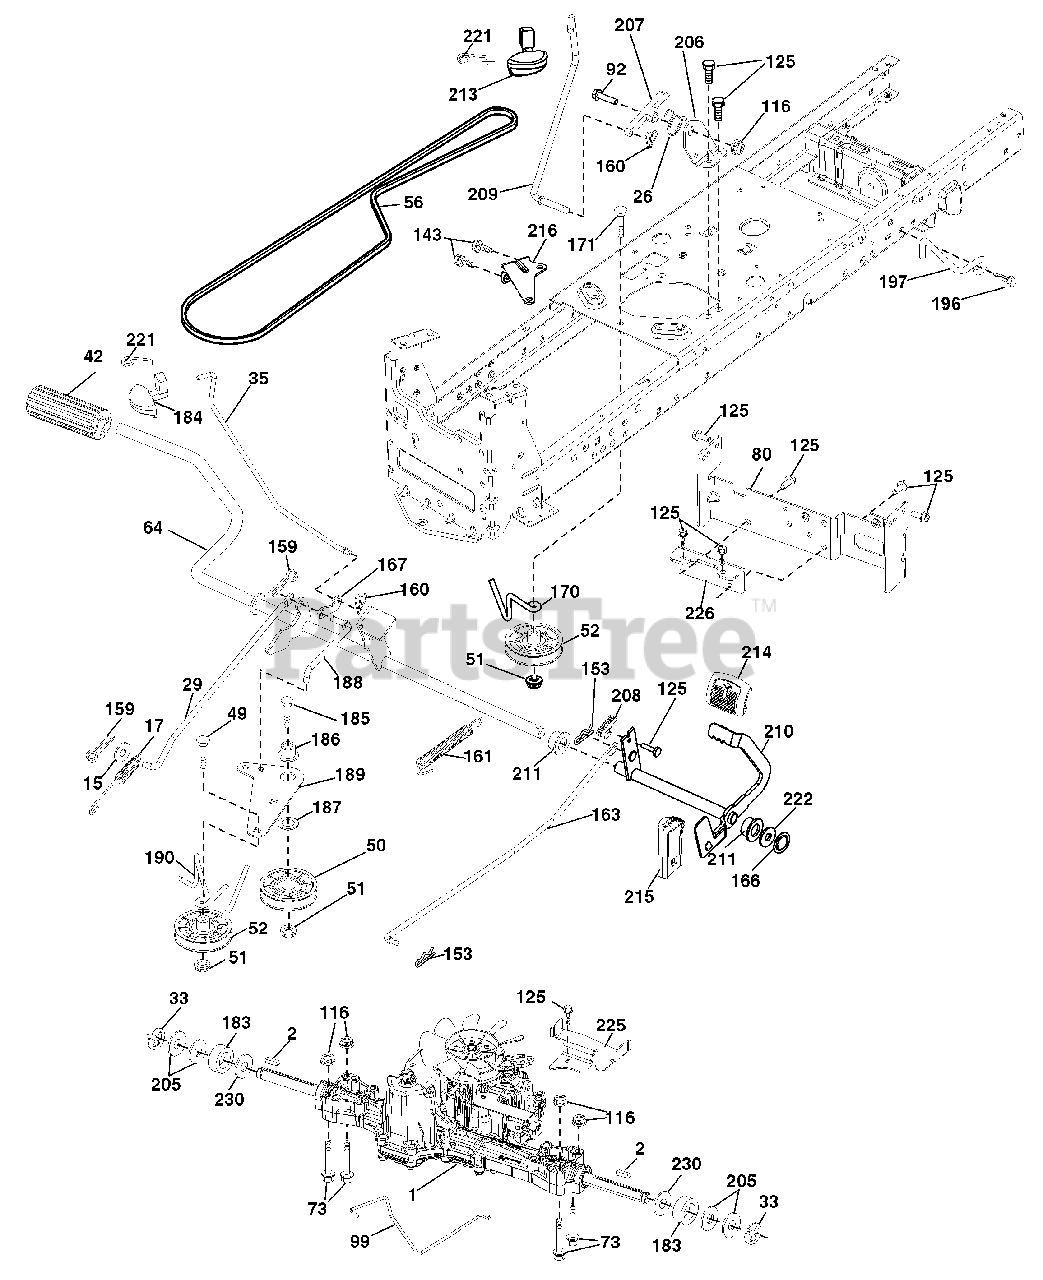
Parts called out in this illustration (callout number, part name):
1	Transaxle, TUFFTORQ K46BT
15	Washer 13/32 x 13/16 x 16 Ga.
17	Spring, Brake
26	Spring Return Cruise
29	Rod, Brake
35	Rod, Brake, Park
42	Cover, Foot Pedal
50	Pulley Idler Flat
51	Lock Nut 3/8-16
52	Idler V-Groove 910" Offset
56	V-Belt, Drive
64	Shaft Asm. Pedal Brake Control
73	Bolt Hex Flghd 5/16-18 Gr. 5
80	Bracket Strap Torque
92	Bolt Fin Hex 5/16-18 unc x 1.25
99	Rod Spring Bypass
116	Nut Lock Hex Flange 5/16-18
125	Screw 5/16-18 x 3/4
143	Screw 5/16-18 x 1/2
153	Retainer Spring
159	Pin Cotter 1/8 x 3/4
160	Retainer Clip
161	Spring, Return, Clutch
163	Rod Pedal Control
166	Nut Push
167	Latch Brake Parking
170	Keeper Belt Centerspan
171	Bolt RDHD SQNK 3/8-16UNC x 2
183	Spacer Split
184	Handle Parking Brake
185	Bolt Rdhd Sqnk 3/8-16 x 2-1/2
186	Spacer Retainer
187	Washer
188	Link Clutch Ground Drive
189	Bellcrank Ground Drive
190	Keeper Bellcrank Ground Drive
196	Screw 3/8-16 x 1
197	Bracket Clutch Anti-Rotation
206	Bracket Mount Latch Cruise
207	Latch Control Cruise
208	Gear Sector Control Cruise
209	Rod Control Cruise
210	Rocker Asm. Pedal Control
211	Bearing Nylon
213	Knob Control Cruise
214	Pedal Forward
215	Pedal Reverse
216	Bracket Pulley Idler
221	Retainer Spring Clip Handle
222	Washer 21/32 x 1-1/4 x 10 Ga.
225	Keeper Belt Trans.
226	Bracket Mount Torque
230	Washer Hardened
